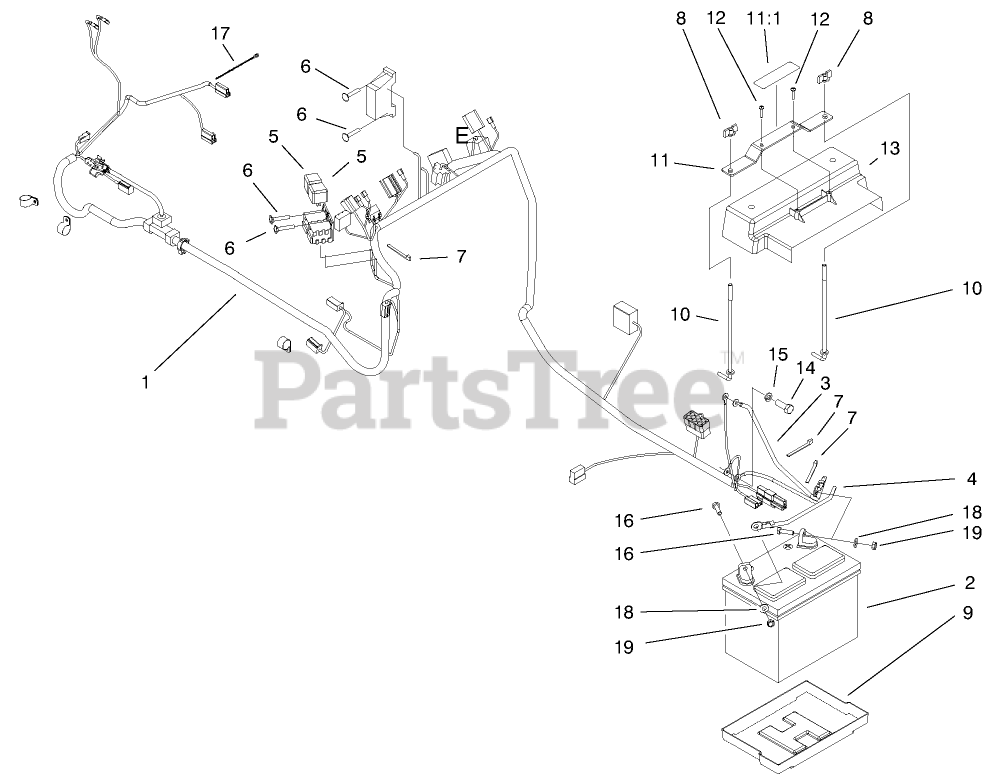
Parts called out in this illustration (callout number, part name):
1	HARNESS-MAIN
4	CABLE-BATTERY, NEGATIVE
5	RELAY
6	SCREW
7	TIE-CABLE
8	NUT-WING
9	TRAY-BATTERY
10	HOOK-RETAIN, BATTERY
11	STRAP ASM
11:1	DECAL-SURFACE, HOT
12	SCREW-PPH
13	SHIELD-BATTERY
13	SHIELD - BATTERY
14	SCREW-HH
15	WASHER-LOCK
16	SCREW-HH
18	WASHER-FLAT
19	NUT-LOCK, NI
99	FUSE-BLADE, 25 AMP
99	FUSE-BLADE, 10 AMP
99	FUSE-30 AMP
